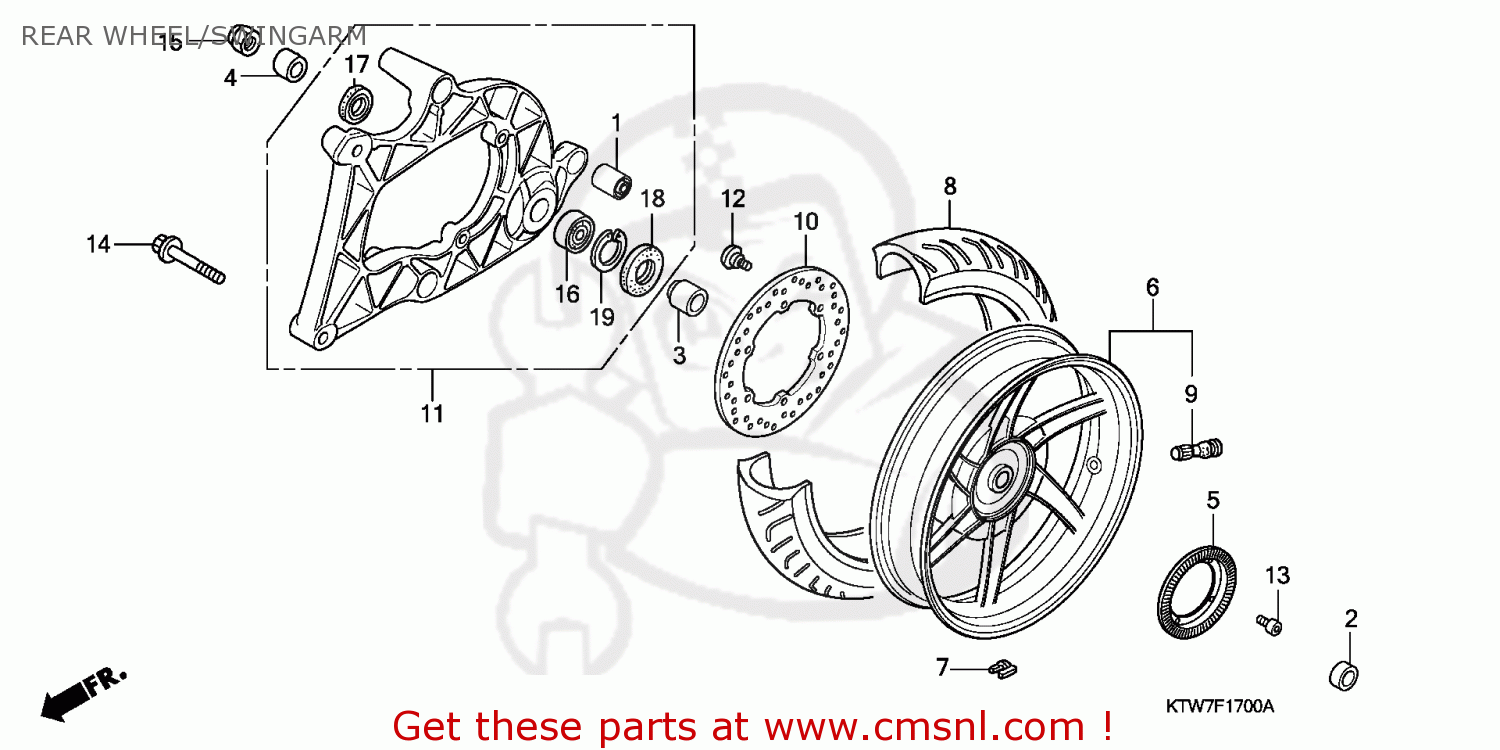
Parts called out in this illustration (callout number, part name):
1	BUSH,DAMPER
2	COLLAR,RR WHEEL S
3	COLLAR,RR AXLE.
4	COLLAR B,RR AXLE
6	WHEEL SUB ASSY,RR
7	WEIGHT,BALANCE 10
8	TIRE,RR(BS).
9	VALVE,RIM (PIRELL
10	DISK,RR BRAKE
11	SWINGARM ASSY
12	BOLT,ENG HANG B
14	BOLT-WASH,10X60
15	NUT,U,16MM
16	B/BRG RAD N/COM
17	DUST SEAL,37X25X6
18	SEAL 25X47X5
19	CIRCLIP IN 47MM
